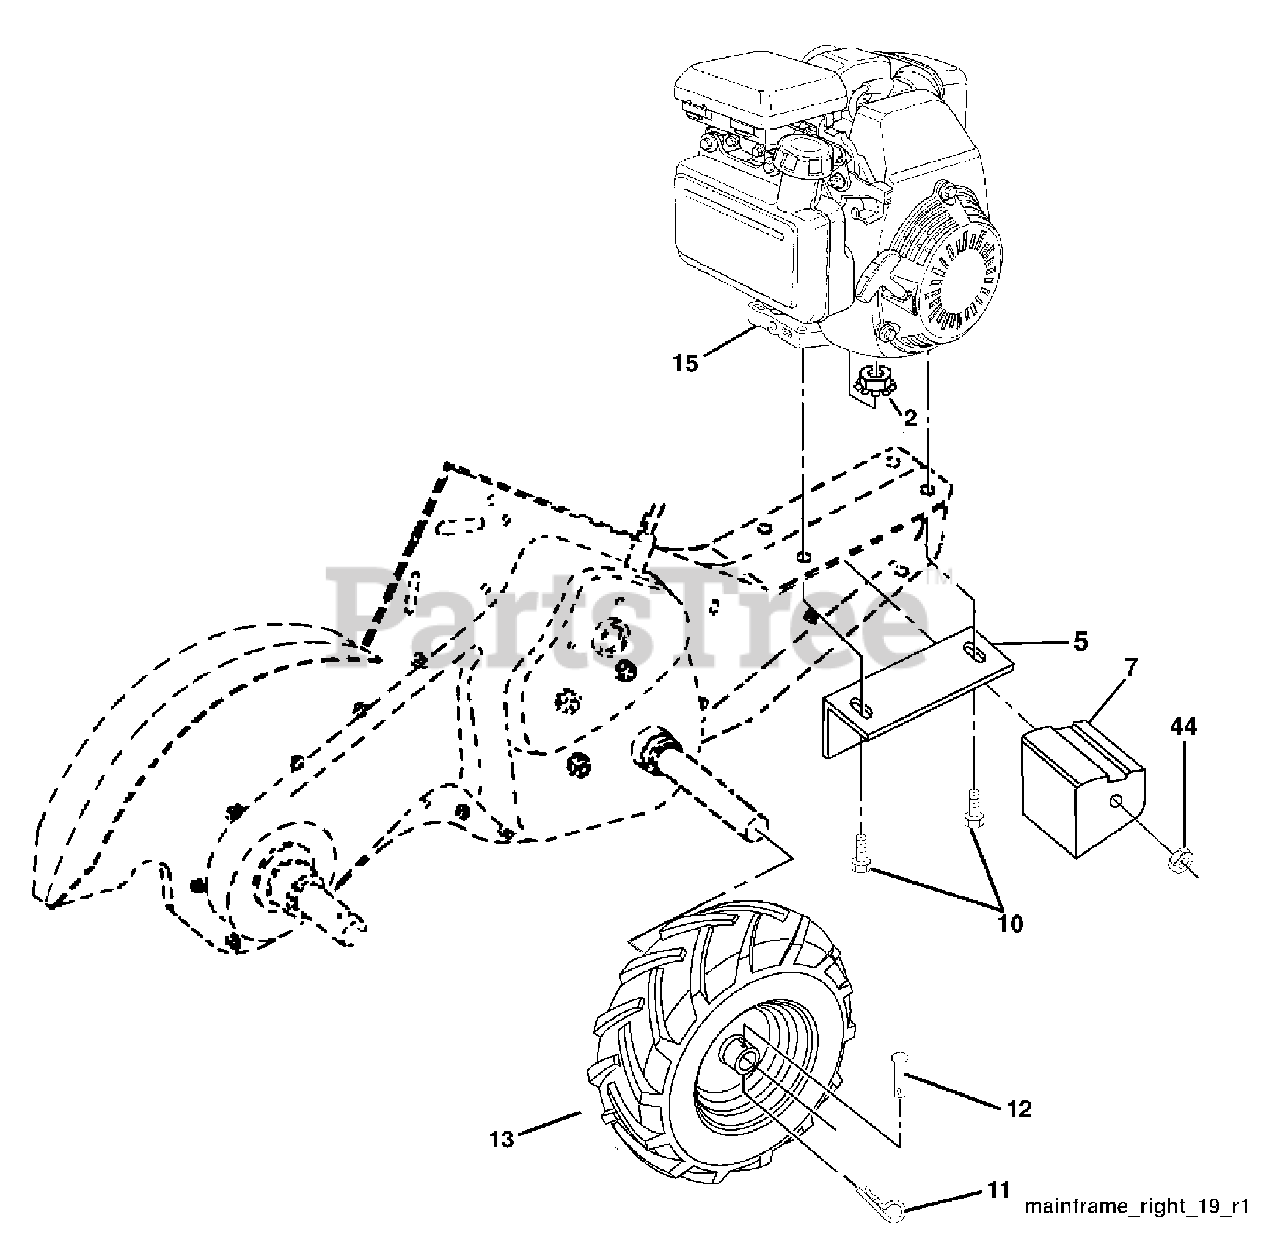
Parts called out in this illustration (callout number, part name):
2	Locknut,Hex,Flange5/16-18
5	Bracket,Reinforcement
7	CounterWeight,R.H.
10	Bolt,Hex5/16-18x1-1/2
11	Clip,Hairpin
12	Rivet,Drilled
44	NutKepsHex3/8-16unc
